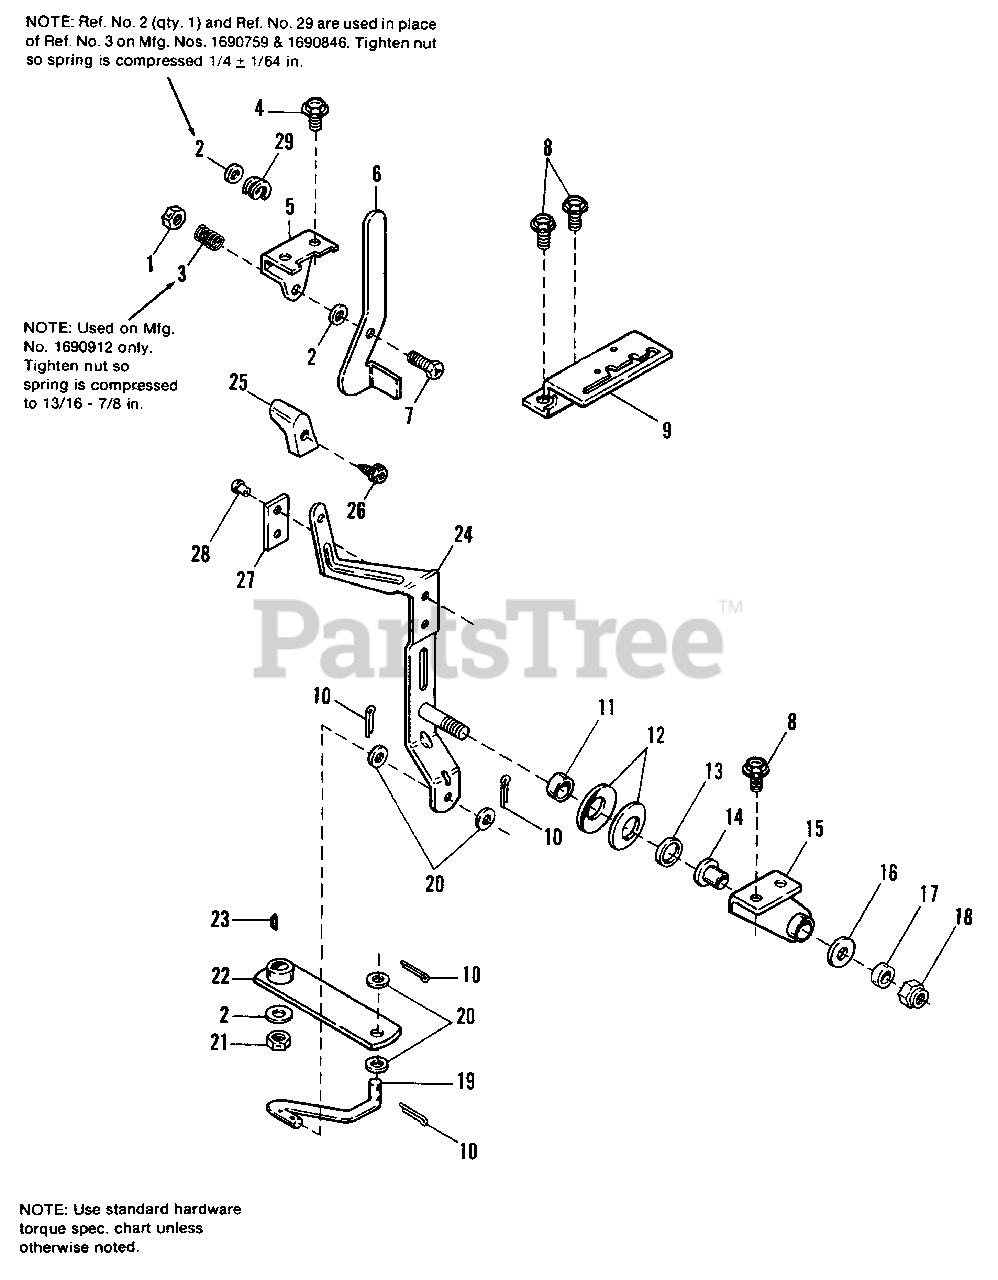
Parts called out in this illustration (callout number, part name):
1	LOCKNUT, Hex, 5/16-18
2	WASHER, Plain, 5/16 (Qty. 3 on 1690759 & 1690846)
3	SPRING, Compression (1690912)
4	SCREW, Taptite, 1/4-20 x 1/2
5	SUPPORT, Handle, Neutral
6	HANDLE, Neutral
7	CAPSCREW, Hex, 5/16-18 x 1-3/4
8	SCREW, Taptite, 5/16-18 x 3/4
10	PIN, Cotter
12	WASHER, Spring
13	WASHER, Special
15	SUPPORT ASSY., Control
18	LOCKNUT, Hex, 5/8-11
19	LINK, Control
20	WASHER, Plain, 13/32 x 1
21	LOCKNUT, Hex, 3/8-16
22	ARM ASSY., Control
23	KEY, Woodruff, #3, 1/8 x 1/2
24	LEVER ASSY., Control
26	SCREW, Plastite, 1/4-20 x 1
27	PLATE, Wear
28	RIVET, Tubular, 3/16 x 5/16
29	WASHER, Spring, Double, 3/8
